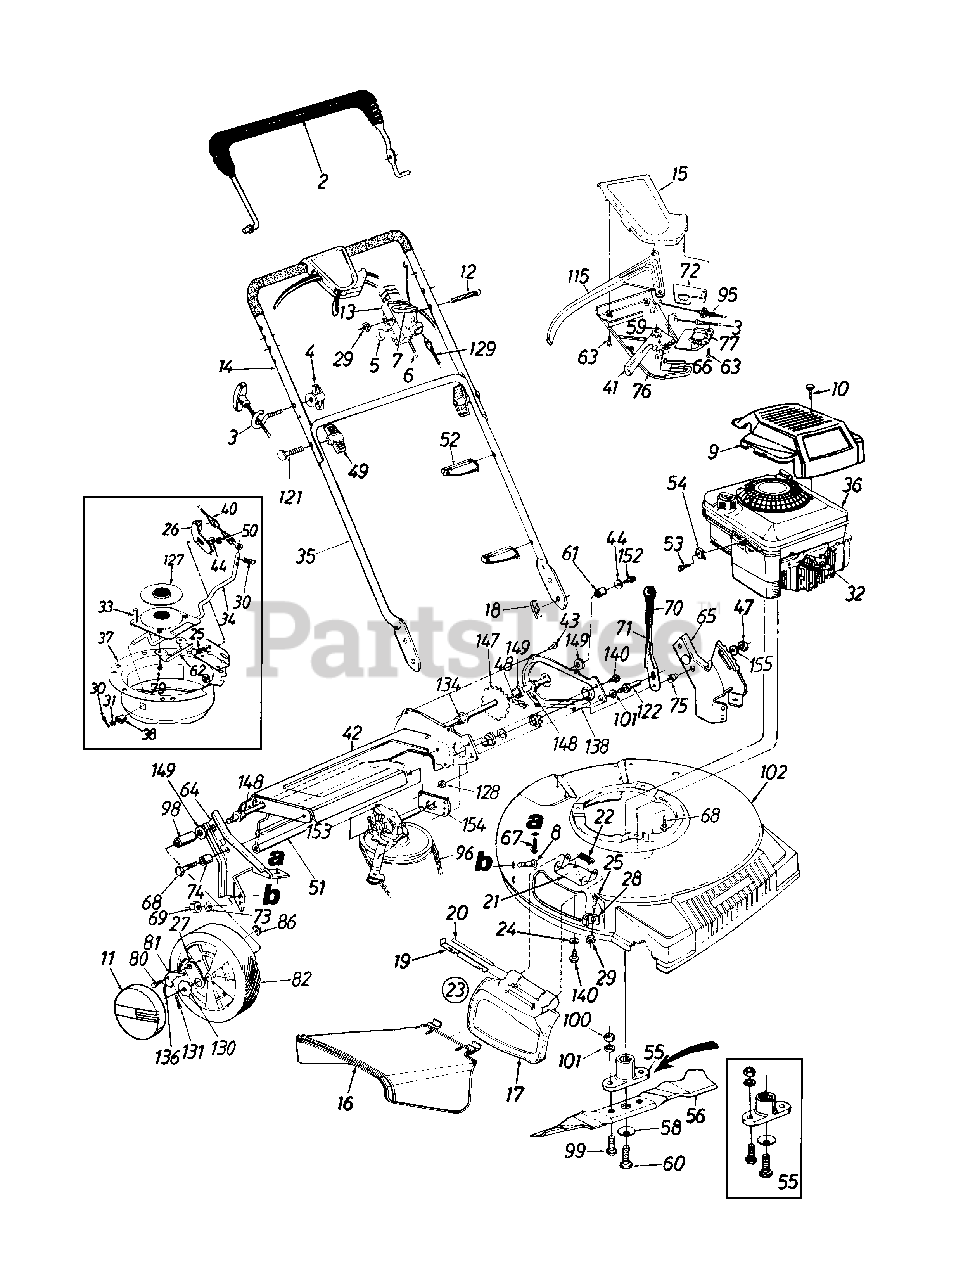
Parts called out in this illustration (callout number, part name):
2	Control Handle
3	Rope Guide
4	Handle Knob 1/4-20 Thd.
5	Curved Spring Wash. .66" I.D.
6	Throttle Wire--55" Lg.
7	Throttle Lever
8	Carriage Bolt 5/16-18 x .62" Lg.
9	XTE Engine Shroud
10	Hi-Lo Screw #10 x 1.25" Lg.
11	Hub Cap
12	Oval C-Sunk Mach. Scr.
13	Throttle Body
15	Upper Control Housing
16	Side Chute Deflector
17	Mulch Plug
18	Internal Cotter Pin 5/16" Dia.
20	Hinge Pin
22	Torsion Spring
23	Mulch Plug Ass'y. Comp.
24	Bell-Wash. .265" I.D. x .75" O.D.
25	Carriage Bolt 1/4-20 x .5" Lg.
30	Cotter Pin 3/32" Dia. x .75"
31	Fl-Wash. .328" I.D. x .68"
32	Spark Plug Insulator
33	Lower Pulley Half Ass'y.
34	Shift Rod
36	Engine--5.5 H.P.
37	Housing Ass'y.
38	Flanged Bushing
40	6 Spd. Cable
41	6 Spd. Shift Lever
44	Bell-Wash. 1/4" I.D.
47	Hex Patch L-Nut 3/8-24 Thd.
48	#48 Chain .500" Pitch x 38 Links
49	Hand Knob
50	Hex L-Nut 1/4-20 Thd.
51	Rear Flap 4.8" x 17.5" Lg.
52	Cable Tie
53	Hex Wash. Hd. Scr. #10-32 x .62" Lg.
54	Casing Clamp
55	Blade Adapter Kit
56	21" Mulching Blade
58	Bell-Wash. .47" I.D. x 1.14" O.D.
59	Gear Insert
60	Hex Bolt 7/16-20 x 2.5"
61	Spacer .513" I.D.
67	Hex B-Tap Scr. 5/16-18
68	Hex TT-Tap Scr. 3/8-16
69	Hex Nut 5/16-18 Thd.
71	Height Adj. Lever
72	6 Spd. Rack Cable Brkt.
73	Bell-Wash. 5/16" I.D.
74	Spacer .383" I.D.
75	Shld. Spacer .5" Dia.
76	Lower Control Housing
77	Cable Mounting Cap
79	Hex Wash. Hd. Tap Scr. 1/4-20 x .38" Lg.
80	Shld. Scr. .342" Dia. x .268
81	Pawl
82	Wheel Ass'y. Comp.
86	Weld Top L-Nut 1/4-20 Thd.
95	S.P. Cable
96	"V"-Belt
98	Sleeve .526" I.D.
99	Hex Bolt 3/8-24 x 1.0" Lg.
100	Hex Nut 3/8-24 Thd.
101	L-Wash. 3/8" I.D.
121	Curved Hd. Bolt 5/16-18 x 2" Lg.
122	Shld. Pin 1.43" Lg.
127	Pulley Half--Serrated
128	Hex Jam Nut 3/8-24 Thd.
129	Control Cable--39"
130	Ratchet Wheel 1.62" O.D.
131	Cotter Pin 1/8" Dia. x 1"
134	Hex Flange Bearing
136	Spring--Nylon
147	Rear Shaft Ass'y. 21.44" Lg.
148	Hex Flange Brg. .506" I.D.
149	Fl-Wash. .531" I.D. x .930"
152	Hex Bolt 1/4-20 x .62" Lg. (Gr. 5)
153	Transmission Comp.
155	Fl-Wash. .385" I.D. x .87" O.D.
